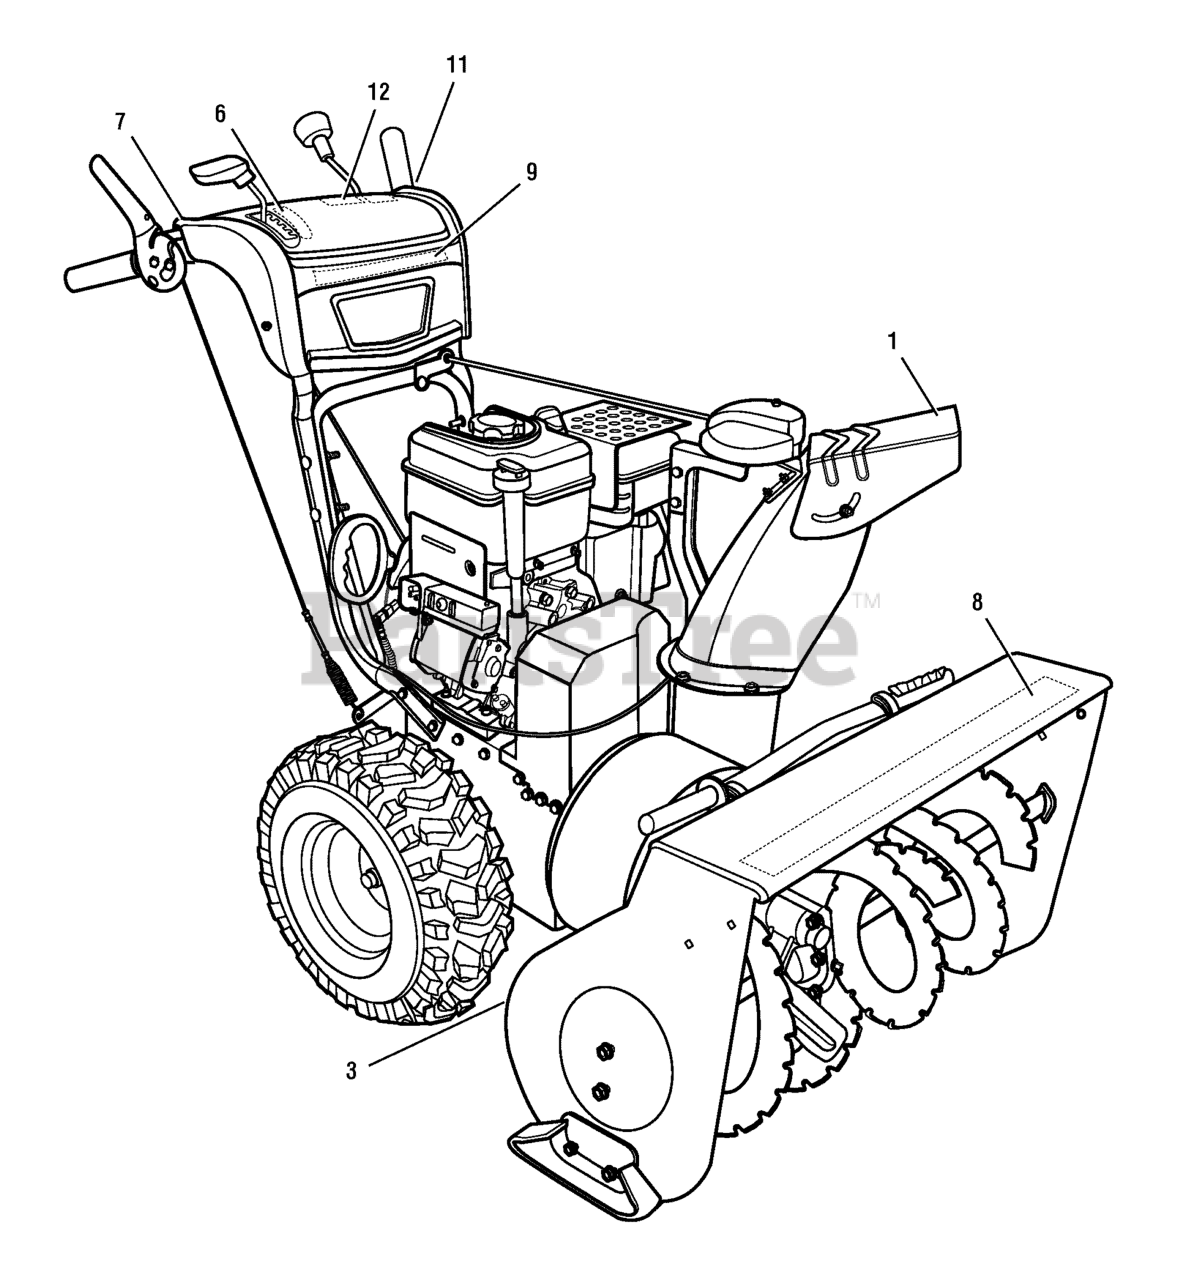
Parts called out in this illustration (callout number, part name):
1	DECAL, THROWN OBJECTS
3	DECAL, ISO AUGER FR/EN
6	DECAL, SHIFT
7	DECAL, AUGER CONTROL SYMBOLS
8	DECAL, MURRAY AUGER HOUSING
9	DECAL, MURRAY DASH
11	DECAL, TRACTION CONTROLS
12	DECAL, CONTROLS
